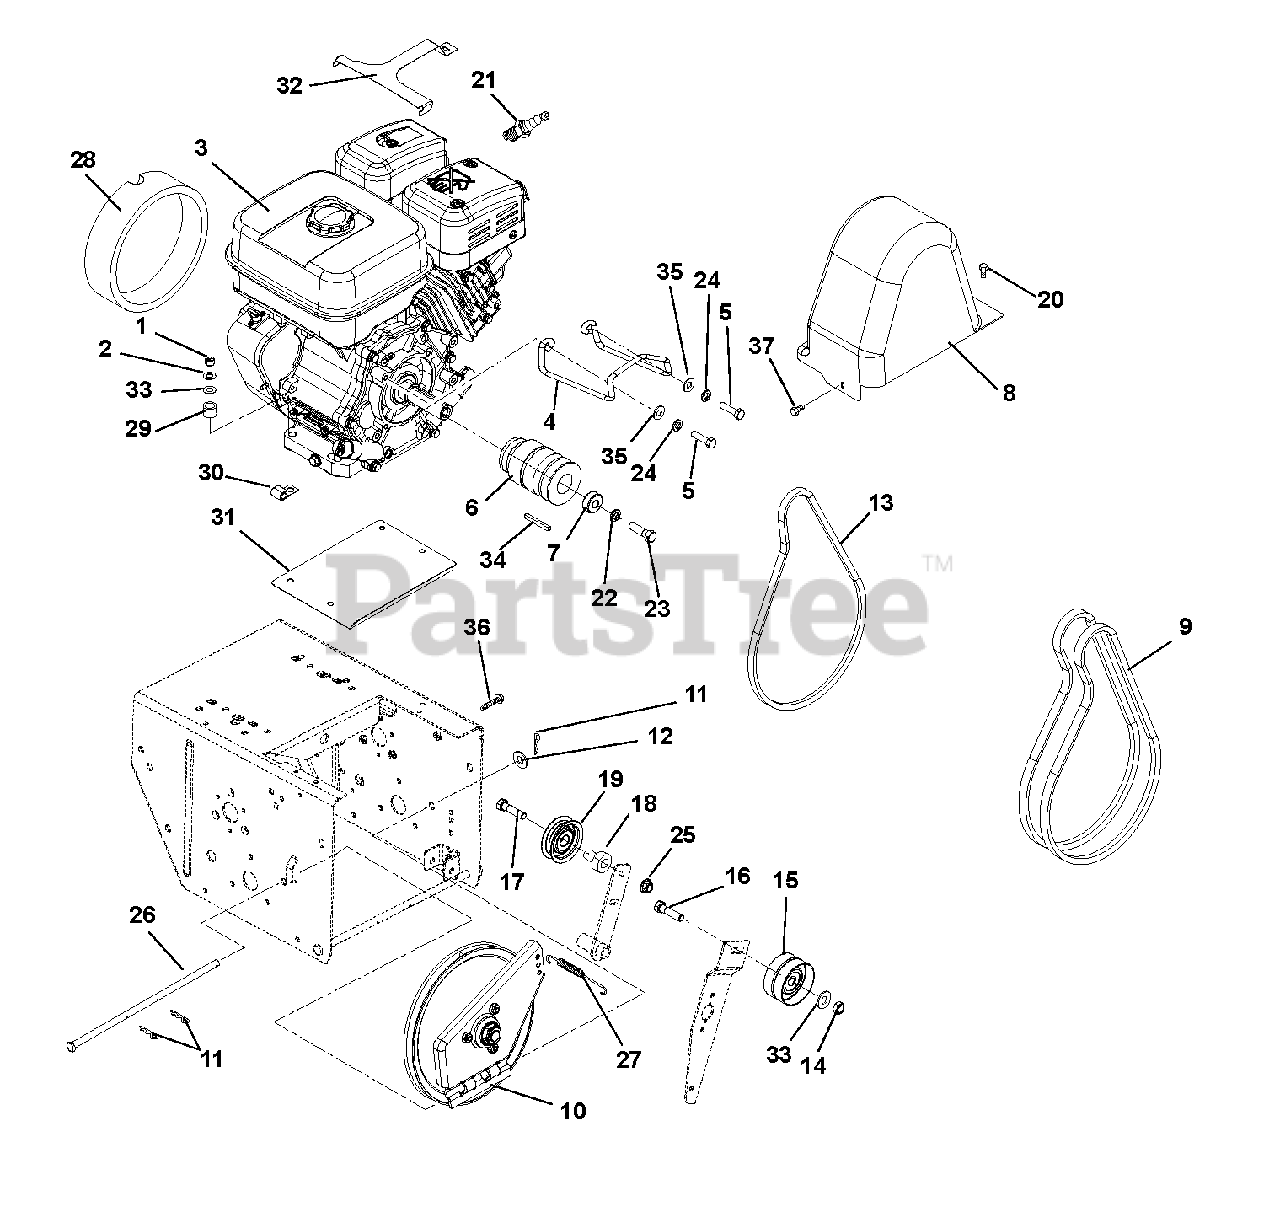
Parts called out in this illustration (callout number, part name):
1	Nut, Hex .31-18
2	Washer, Lock .312 x .097
3	Engine, Subaru EX27 All-Season
4	Belt Finger
5	Bolt, Hex .31-24 x .75
6	Sheave, Engine
7	Bushing, Spacer
8	Cover, Belt
9	V-Belt, Matched Set, Brush
10	Plate, Swing Assembly
11	Hair Pin
12	Washer, Flat Steel .406 x .812 x .065
13	V-Belt, Drive
14	Nut, Locking Center Jam .38-16
15	Idler, Flat
16	Bolt, Round Head Square Short Neck .38-16 x 1.75
17	Bolt, Hex .31-18 x 1.25
19	Idler
20	Screw, Tapping Large Hex Washer Head Thread Rolling .25-20 x .50
21	Plug, Spark
22	Washer, Lock .44 x .109
23	Bolt, Hex .44-20 x 1.50
24	Washer, Lock .312 x .097
25	Nut, Locking Top Flange .31-18
26	Rod, Pivot
28	Foam Cover, Recoil
29	Bushing, Sleeve
32	Guard, Snow
33	Washer, Flat Steel .38 x .875 x .083
34	Key .25 x .25 x 2.25
35	Washer, Flat Steel .344 x .688 x .065
36	Screw, Tapping Hex Washer Head Thread Rolling .25-20 x 1.50
37	Screw, Tapping Captive .25 - 20 x .50
